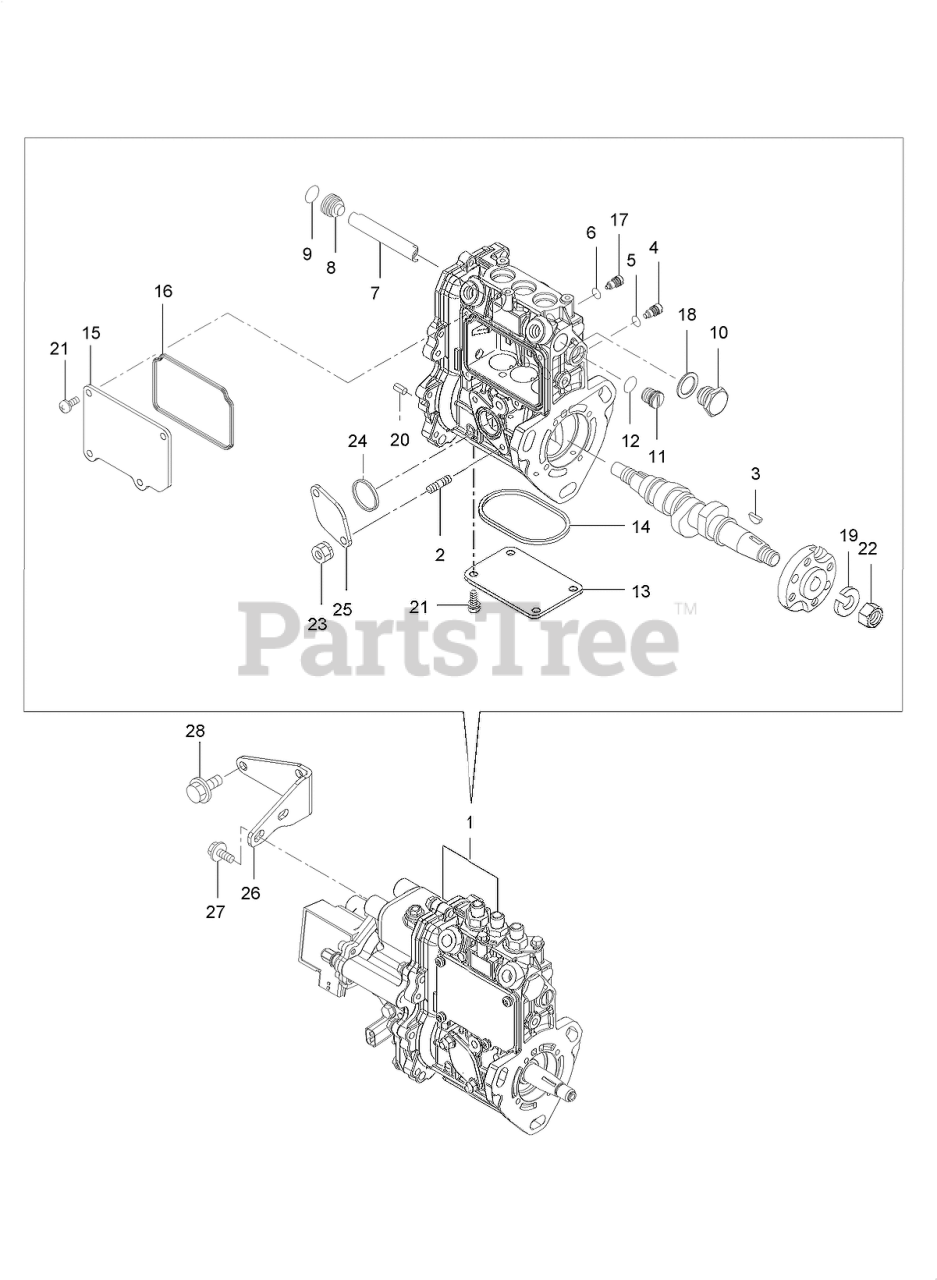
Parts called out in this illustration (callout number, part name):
1	FIE ASM
2	BOLT-STUD
3	FEATHER KEY-WOODRUFF
4	STOPPER
7	DEFLECTOR
8	PLUG-DEFLECTOR
10	PLUG-DEFLECTOR
11	PLUG-RACK
17	STOPPER-RACK
18	WASHER-SEAL
19	WASHER-SPRING
20	PIN-SPRING
25	COVER-PUMP
26	SUPPORT
